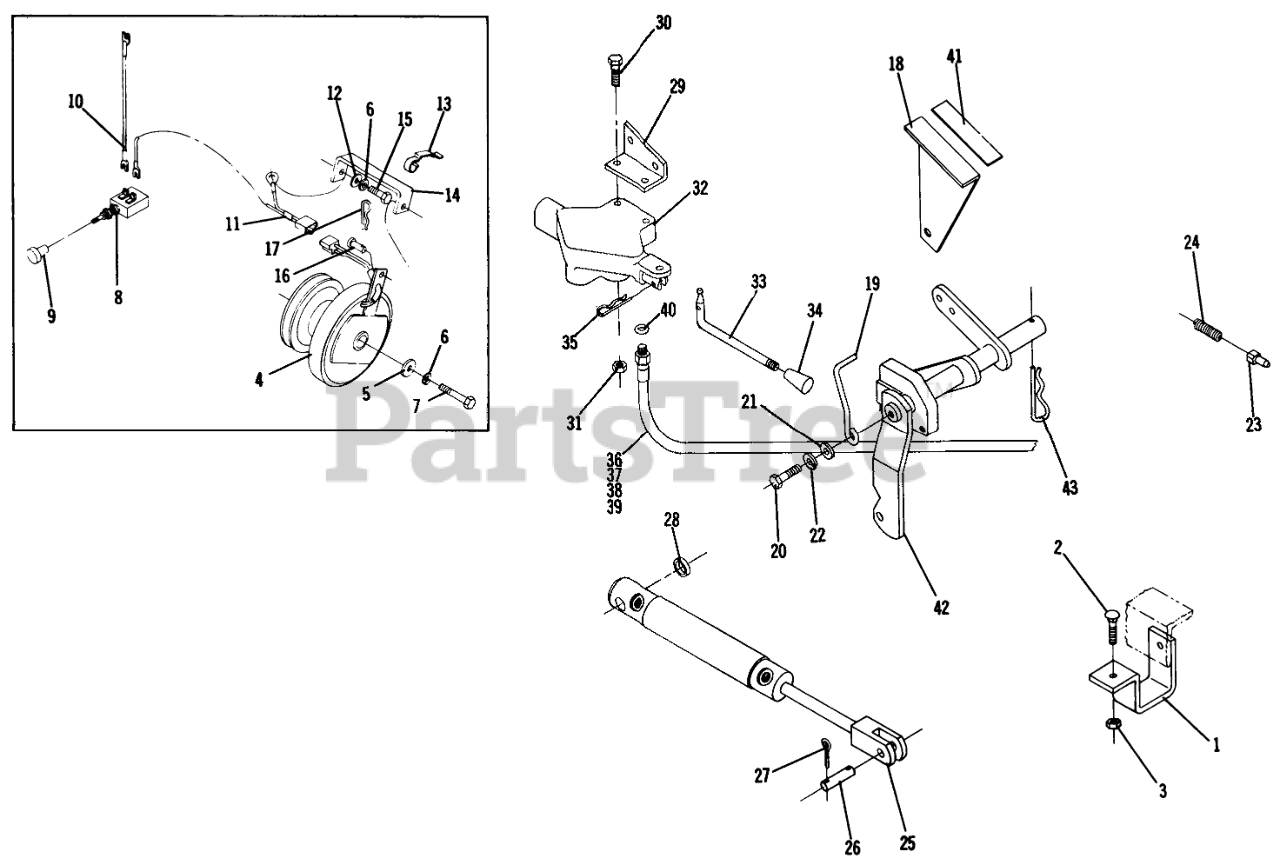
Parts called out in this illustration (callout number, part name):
1	Bracket
2	Bolt-Carriage 5/16-18
3	Nut 5/16-18
5	Washer
6	Lockwasher 3/8
7	Bolt Hex 7/16-20 x 2
11	Wire-Clutch to switch
12	Washer
15	Bolt, 7/16 14 x 1
17	Hairpin
19	Arm
20	Bolt 5/16-18 x
21	Washer
22	Lockwasher
27	Cotter Pin
30	Bolt 1/4 20 x 1 1/4
31	Nut-Nylok
35	Hairpin
40	O RING
41	Decal
43	Hairpen
